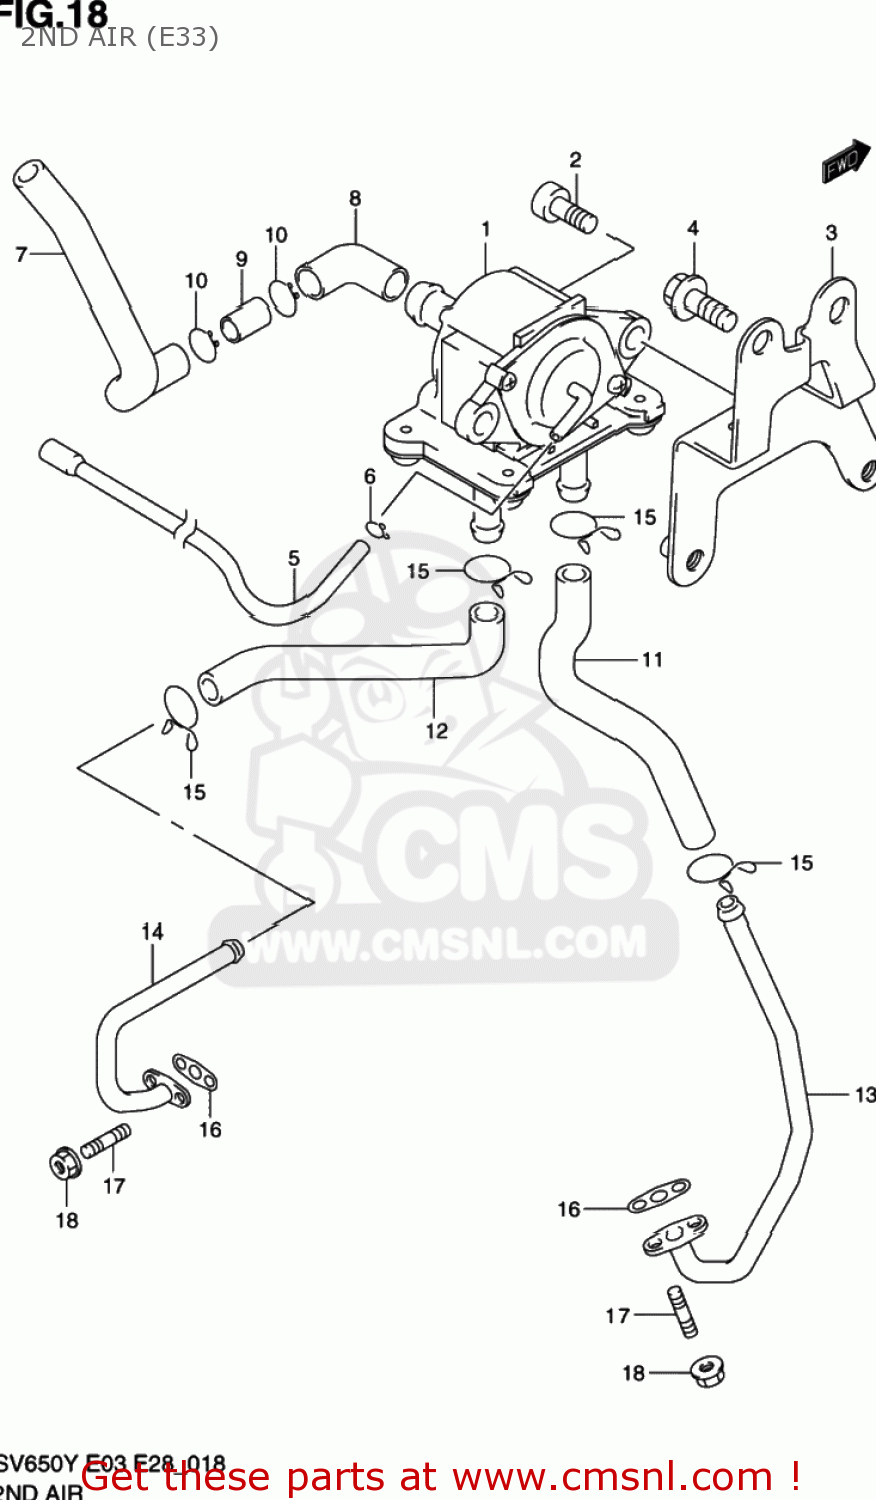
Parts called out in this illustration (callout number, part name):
1	VALVE ASSY,2ND AIR
2	BOLT,OIL FILLE
3	BRACKET,2ND AIR VALVE
4	SCREW
5	HOSE(4X7X600)
6	CLIP
7	HOSE,2ND AIR CLEANER
8	HOSE,2ND AIR CLEANER JT
9	JOINT,2ND AIR CLEANER HOSE
10	CLIP
11	HOSE,2ND AIR VALVE FR
12	HOSE,2ND AIR VALVE RR
13	PIPE COMP,SECOND AIR,FRONT
14	PIPE COMP,SECOND AIR,REAR
15	CLIP
16	GASKET,SECOND AIR PIPE (N (NAS)
17	STUD BOLT
18	NUT
